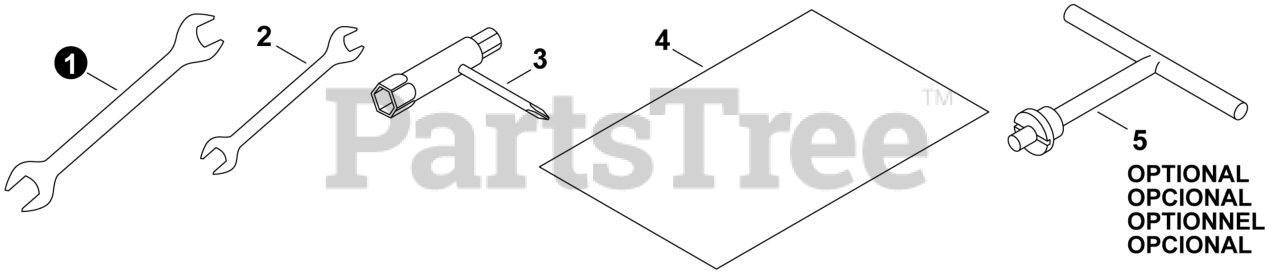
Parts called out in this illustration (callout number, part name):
1	SPANNER 14x17
2	SPANNER 10x12
3	WRENCH, T 17x19 MM
4	BAG, POLY
5	TOOL, DRIVER
